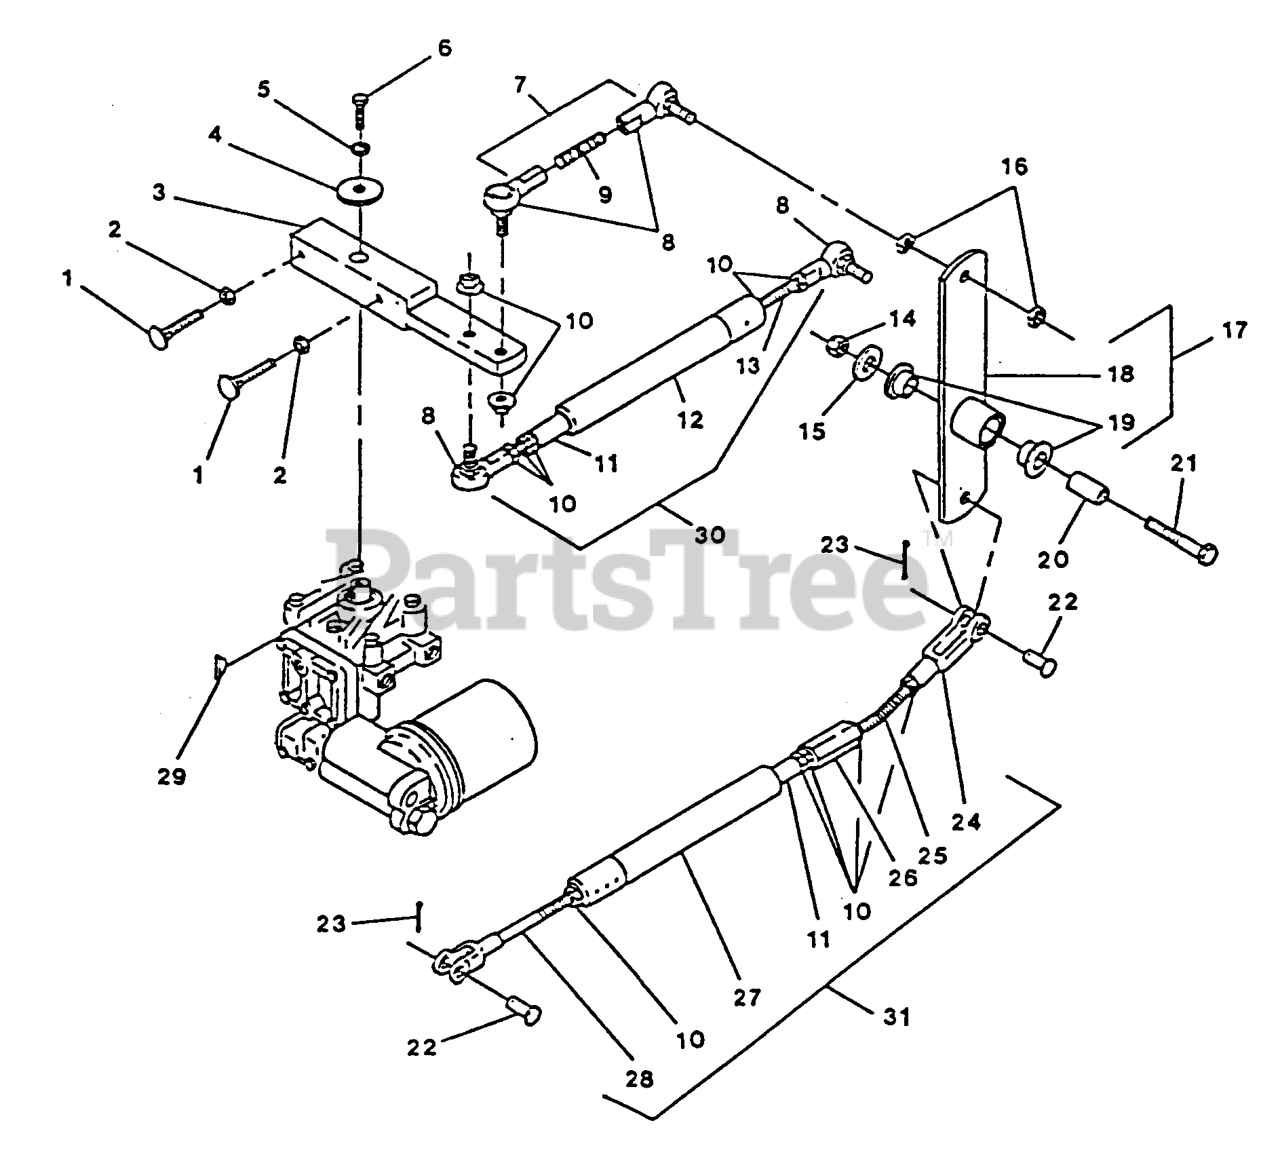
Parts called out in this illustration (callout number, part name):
3	WLD,ARM TRANSAXLT
4	WASHER-RETAINER, PULLEY
5	WASHER-LOCK
8	BALLJOINT
9	ROD END PLTD.
11	BUSHING,SPRING GUIDE
13	ROD,END
18	WLD,IDLER LINKAGE
19	BEARING-CONTROL
20	BUSHING,MOTION LEVER
22	PIN-CLEVIS
24	YOKE-ADJUSTABLE
28	LINKAGE-CLEVIS .31
